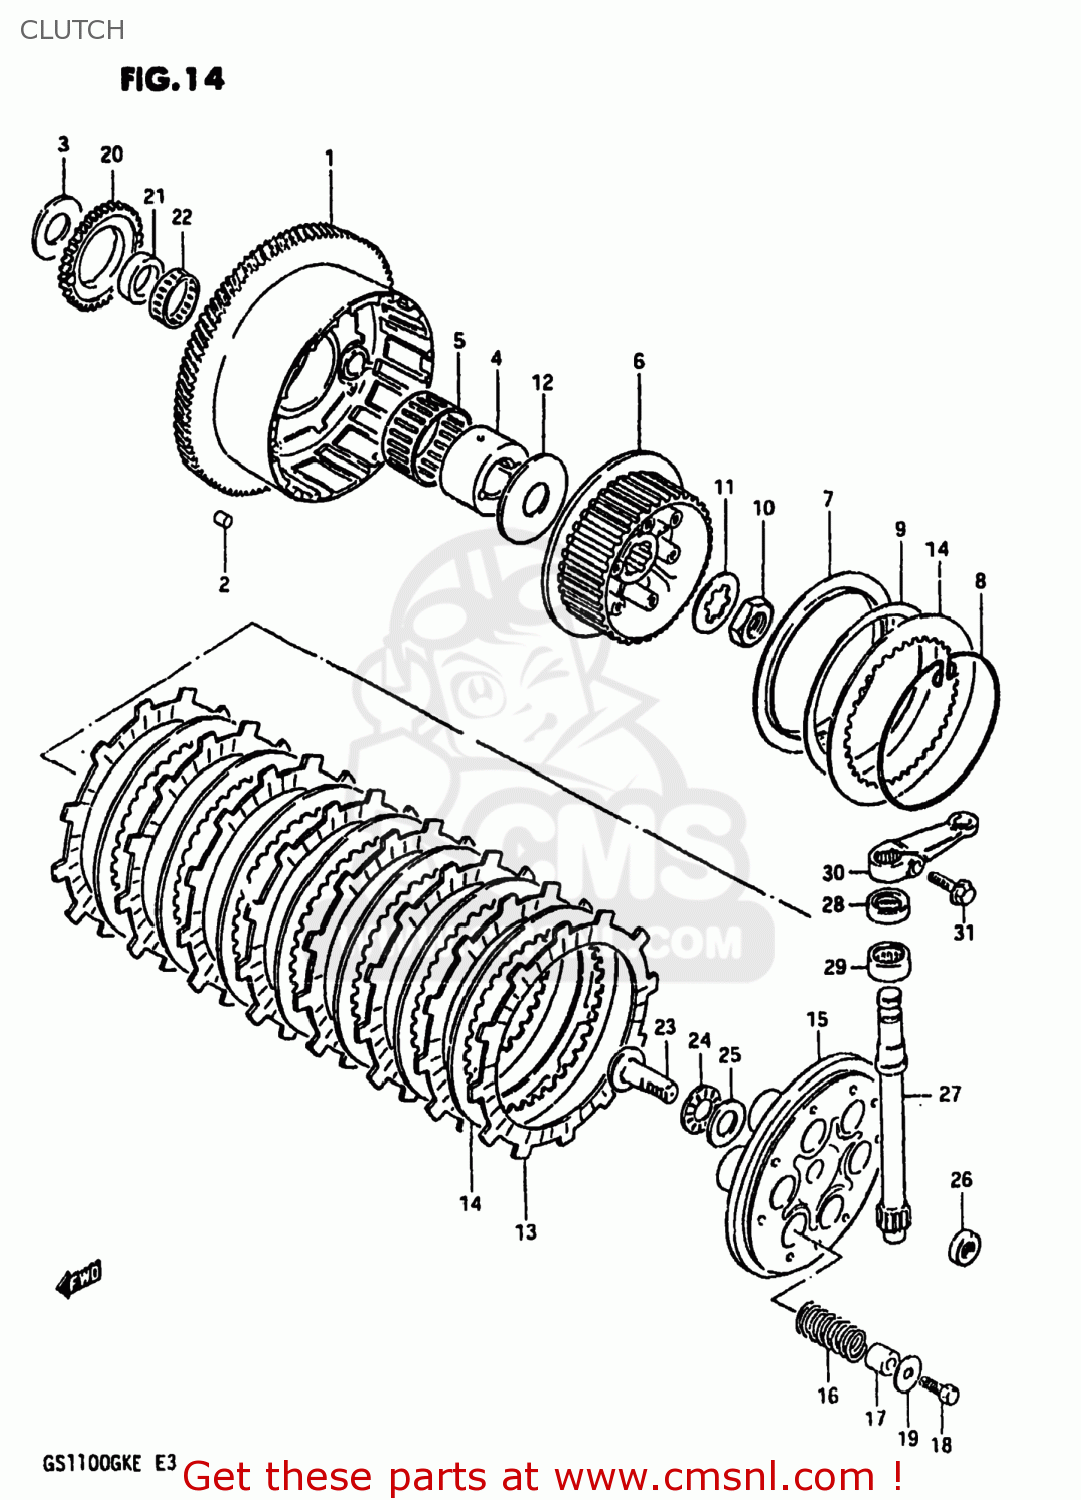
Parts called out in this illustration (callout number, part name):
1	GEAR ASSEMBLY,PRIMARY DRIVE
2	CUSHION,PRIMARY DRIVEN GEAR
3	WASHER
4	SPACER
5	BEARING(51X56X28)
6	HUB,CLUTCH SLEEVE
7	SEAT,WAVE WASHER
8	RING,STOPPER
9	WASHER
10	NUT
11	WASHER,LOCK
12	WASHER(25X66X3.5)
13	PLATE,CLUTCH DRIVE (MCA)
14	PLATE,CLUTCH DRIVEN (NAS)
15	PLATE,CLUTCH PRESSURE
16	SPRING
17	SPACER
18	BOLT
19	WASHER
20	GEAR,ENG OIL PUMP DRIVE(NT:34)
21	SPACER,OIL PUMP DRIVE GEAR
22	BEARING(36X40X10)
23	RACK,CLUTCH RELEASE
24	BEARING(15X28X2)
25	WASHER
26	SEAL,OIL(10X16X5)
27	PINION,CLUTCH RELEASE
28	OIL SEAL
29	BEARING(15X22X12)
30	ARM,CLUTCH RELEASE
31	BOLT,REAR
